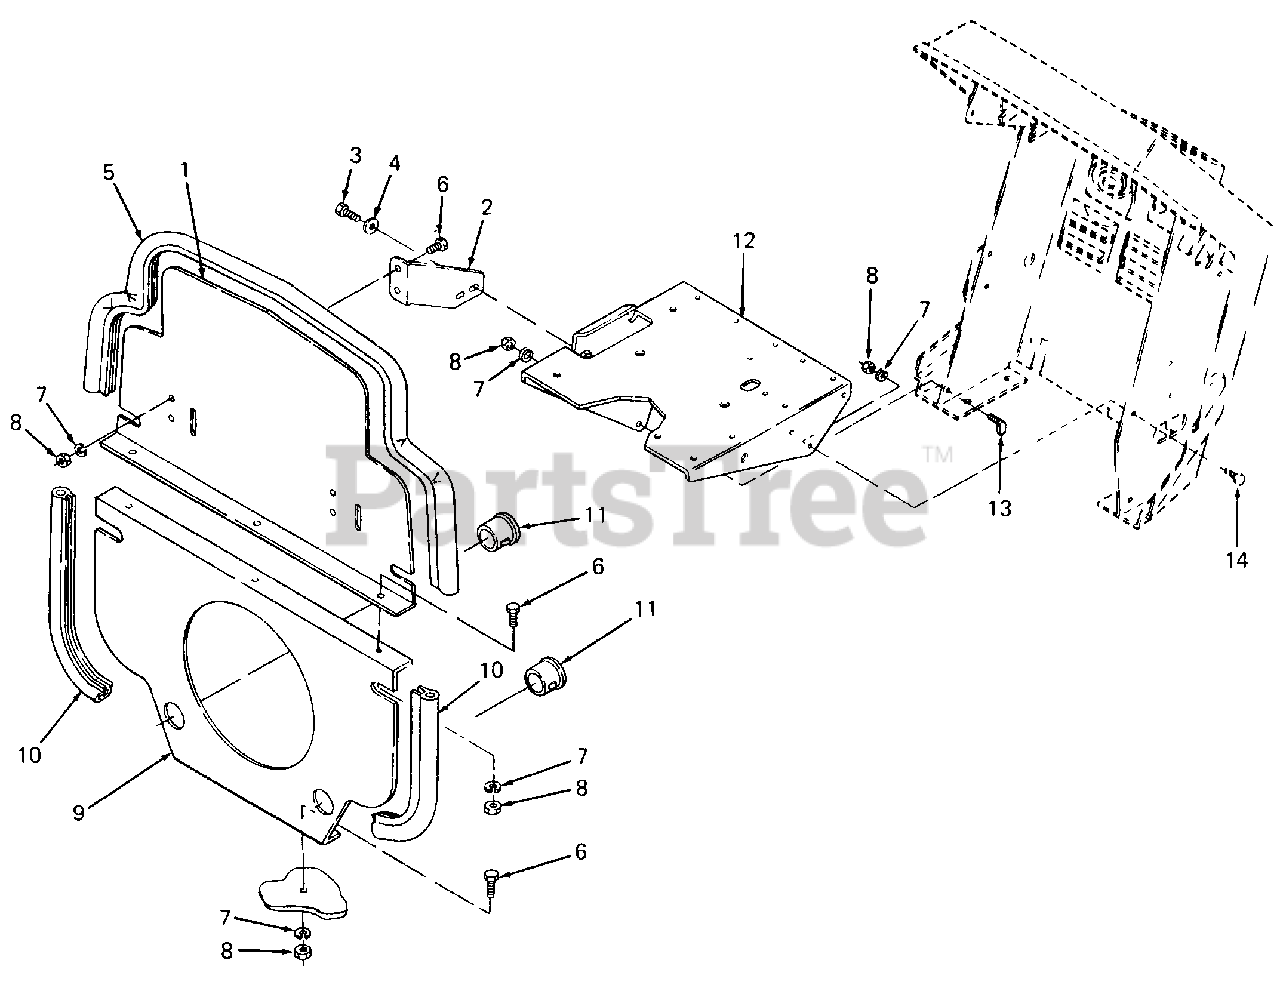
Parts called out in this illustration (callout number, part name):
3	Screw, Hex Cap, 5/16-18 X .50 Lg GR5
4	Washer, Bell, .345 X .88 X .060 Thk
5	Seal, Bulkhead, 36" Lg
6	Screw, Hex Cap, 1/4-20 X .50 Lg GR5
7	Washer, Lock, 1/4
8	Nut, Hex, 1/4-20 GR5
9	Bulkhead, Lower
10	Seal, Bulkhead, 10" Lg
11	Bushing, Snap, 7/8 ID
12	Tray Assy, Battery
13	Bolt, J-Type, 1/4-20
14	Screw, Hex Cap, 1/4-20 X .62 Lg GR5
